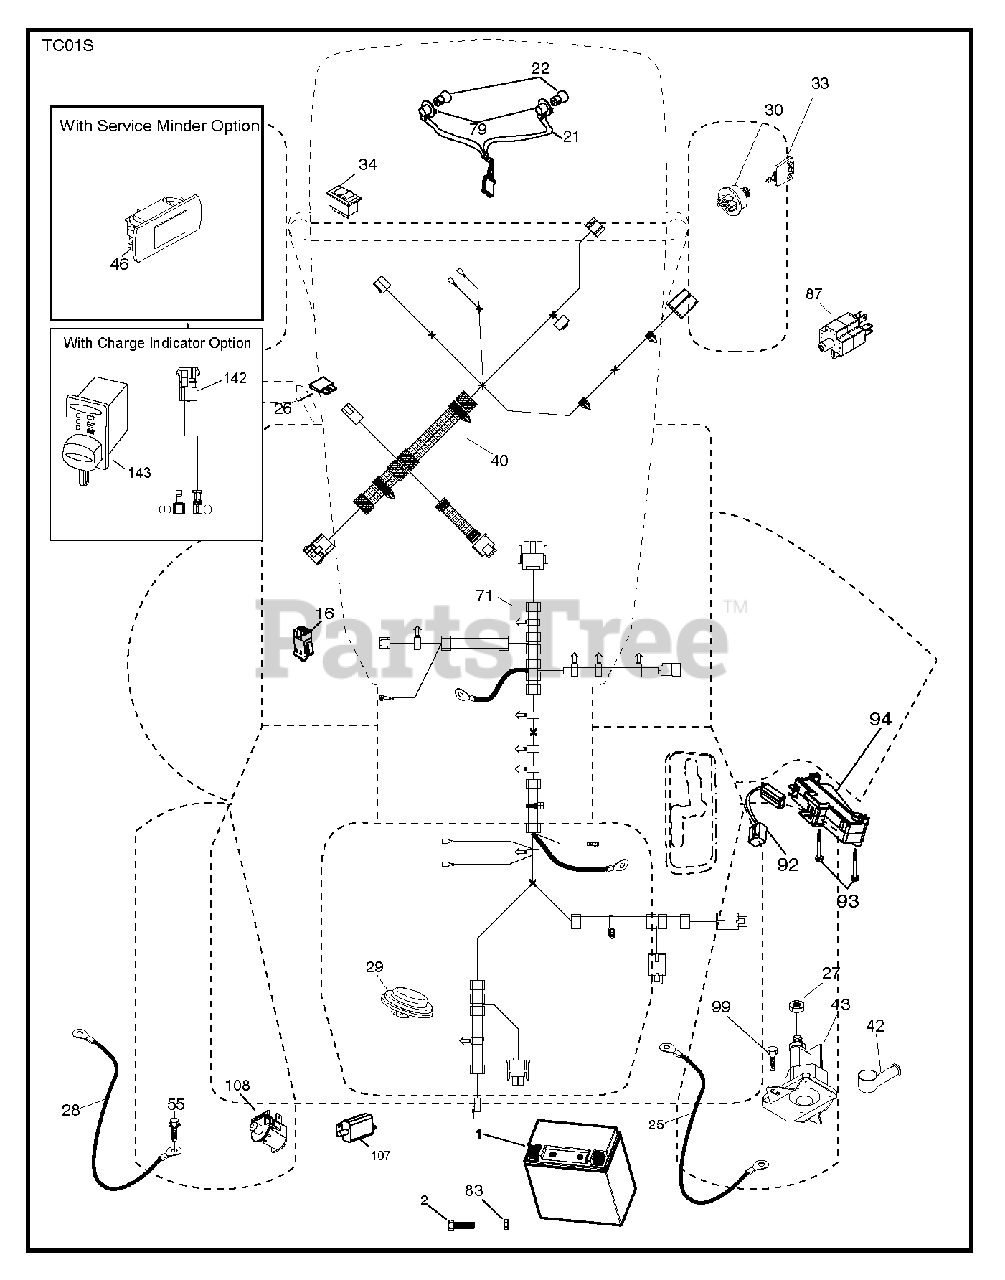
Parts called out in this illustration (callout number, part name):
1	BATTERY BATTERY 14AH 12V LEOC
2	SCREW.HEX.HEAD.CAP.M6 X1.12W
16	SWITCH INTERLOOK PUSH-IN
21	HARNESS.LIGHT W/4152J BULBS
25	CABLE.RED.8AWG.TCRD.GEN1
26	FUSE 20AMP
27	NUT
28	CABLE.BLACK.8AWG.TCRD.GEN1
29	SWITCH.SEAT.DELTA.OPC.
30	SWITCH.IGN.DELTA.W.LGH.ROS
33	KEY.CHAIN.BLISTER.PACK.GEN.INT
40	HARN.DASH.CRD.CC.SQ.RDSTRT
42	TERMINAL COVER
43	SOLENOID.W/BRASS.PLUNGER
55	SCREW 5/16"
71	HARNESS.CHASSIS.TCRD.RDYSTRT
79	BULB HOLDER ASM.
83	NUT NUT SQUARE
87	RP SWITCH.RAILMOUNT.NO-NC-NC
92	HARNESS.PIGTAIL.CONSLE
93	SCREW.PLASTITE
94	MODULE.REVERSE.ROS
99	SCREW
107	.WITCH.FULL BAGGER.INDICATOR
108	SWITCH.SNAPMOUNT.NC
142	CHARGE.PORT.PIGTAIL HARNESS
143	CHARGE.PORT
